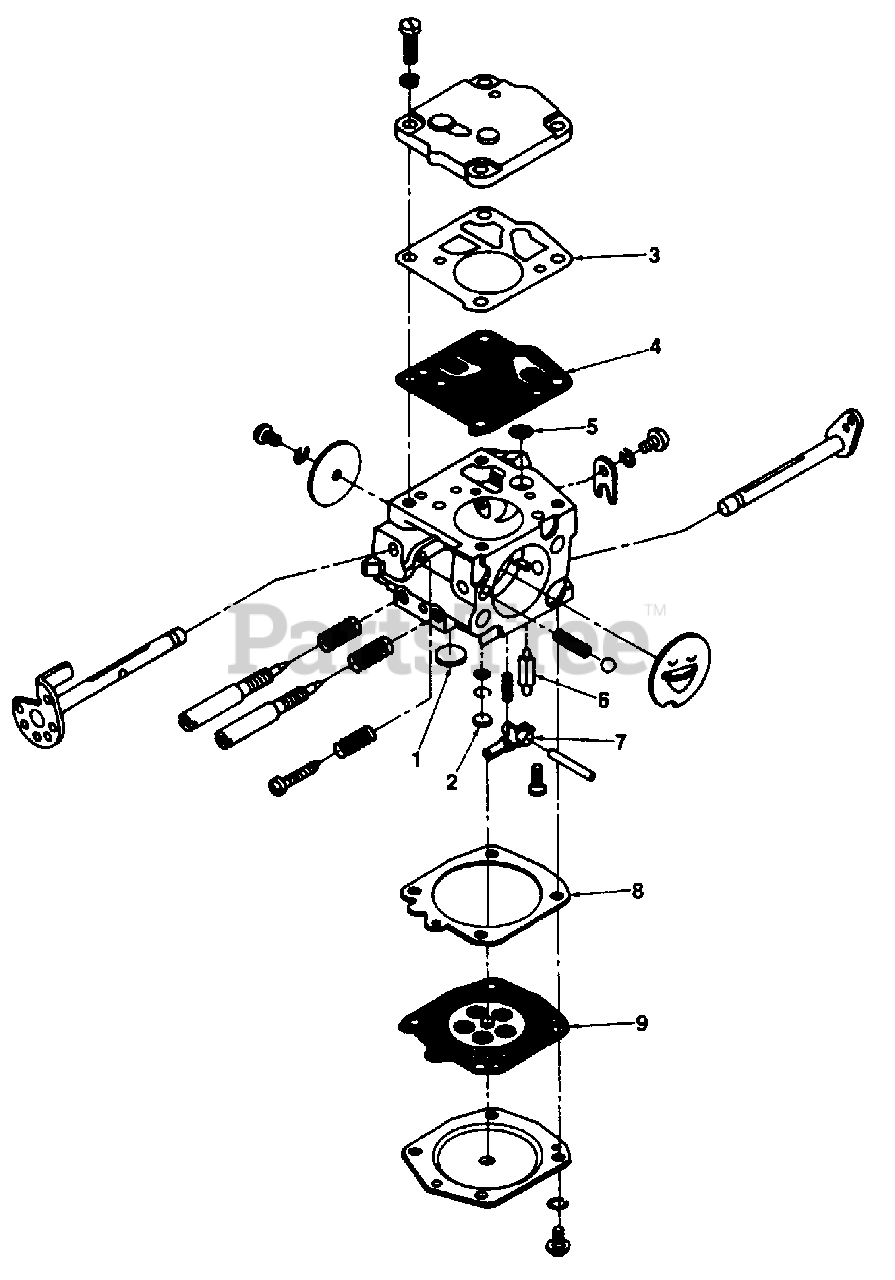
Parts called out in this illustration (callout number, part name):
1	REPAIR KIT
2	REPAIR KIT
3	REPAIR KIT
4	REPAIR KIT
5	REPAIR KIT
6	REPAIR KIT
7	REPAIR KIT
8	REPAIR KIT
9	REPAIR KIT
